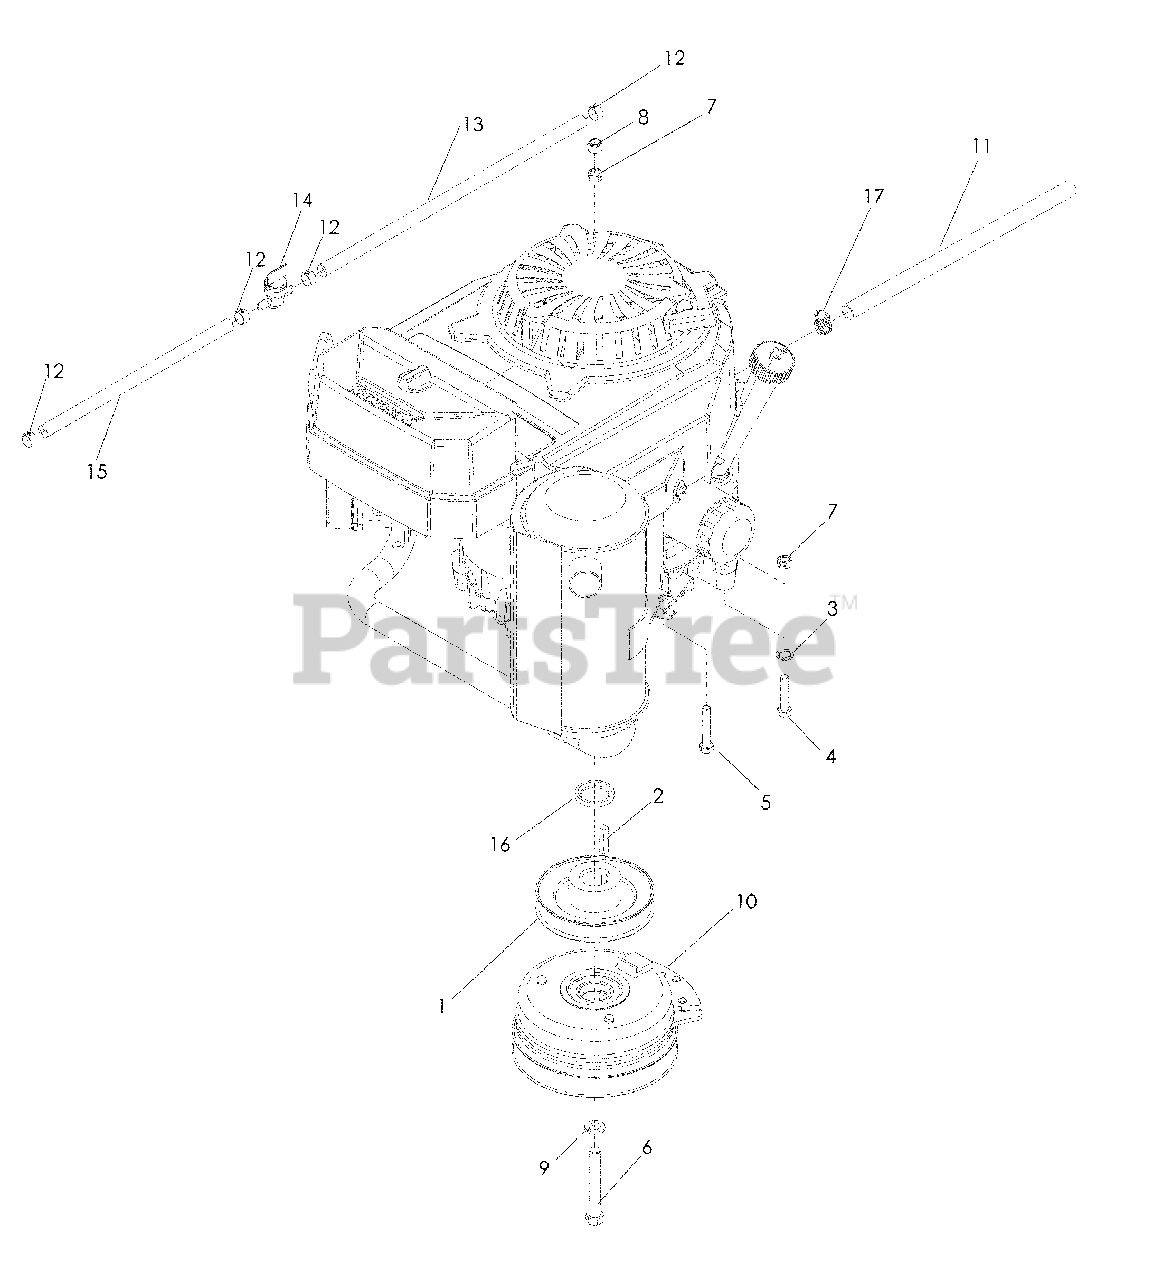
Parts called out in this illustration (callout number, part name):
2	KEY, ¼" SQ. x 1 1/8"
3	WASHER, 3/8 INTR TH
4	HCS, 5/16-18 x 1½
5	HCS, 5/16-18 x 1¾
6	HCS, 7/16-20 x 3
7	NUT 5/16-18 HEX CTRLK
8	NUT 5/16-18 HEX NYLOC
9	LOCKWASHER, 7/16
10	CLUTCH, 125 FT/LB
11	HOSE, OIL DRAIN
12	CLAMP, HOSE
13	FUEL LINE, 14"
14	FUEL VALVE
15	FUEL LINE, 10"
17	CLAMP, HOSE, 5/16-7/8
